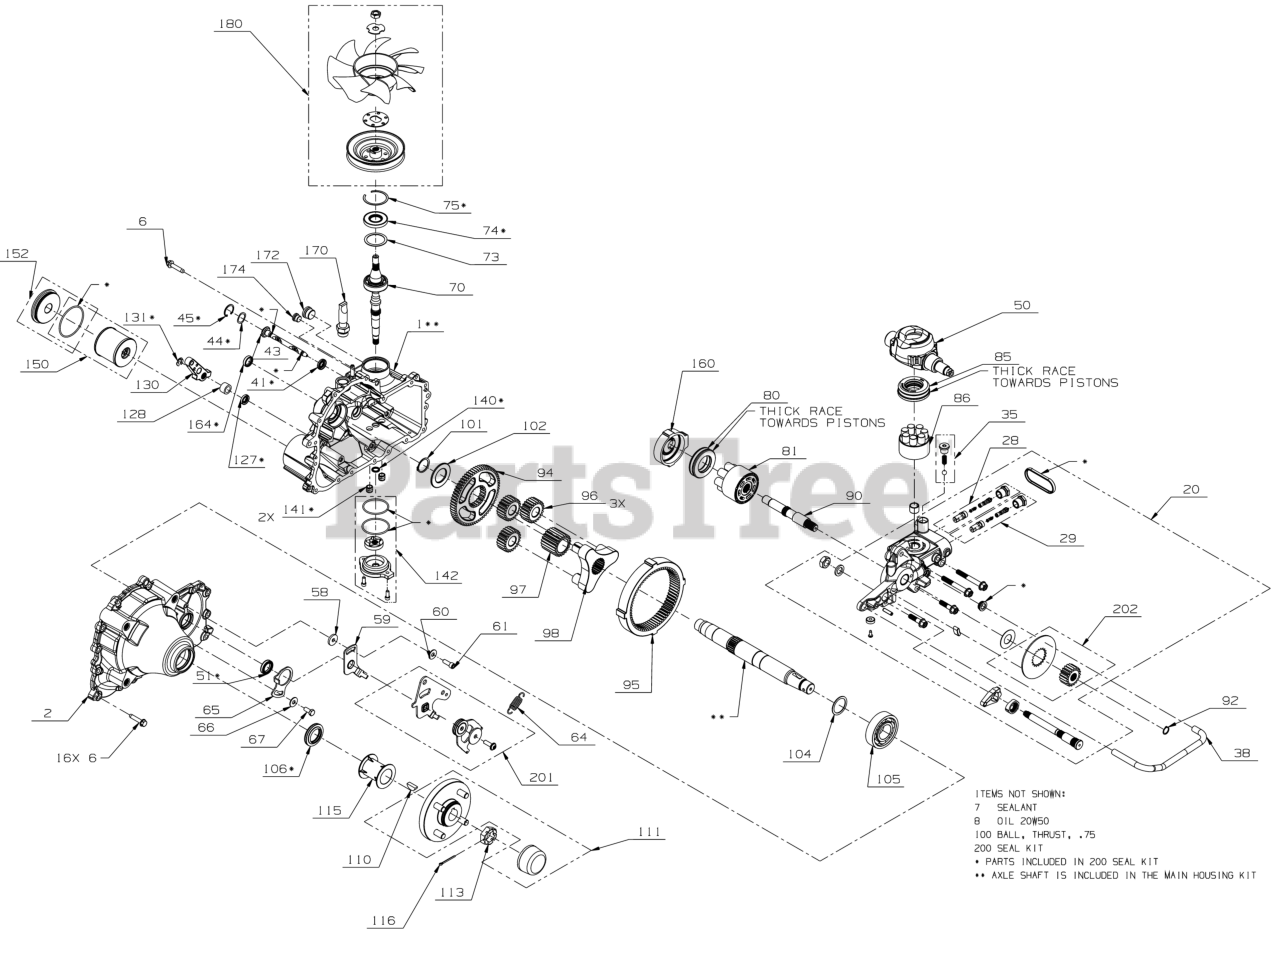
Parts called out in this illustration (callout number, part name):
1	MAIN (RH) KIT
2	SIDE HOUSING (RH) KIT
6	HOUSING SCREW
7	SEALANT-HOUSING
20	CENTER SECTION (RH) KIT
28	SHOCK VALVE KIT
29	SHOCK VALVE KIT
35	CHARGE RELIEF KIT
38	FILTER TUBE-RH
41	LIP SEAL 12 X 24 X 5
43	ACTUATOR BYPASS ASM
44	WAVE WASHER 1.00 X .78 X .07
45	RETAINING RING HO-102
50	16CC MACHINED SWASHPLATE
51	LIP SEAL 22 X 32 X 7
58	SPACER .32 x 1.005 x .179
59	ARM-NEUTRAL (RH)
60	FLAT WASHER
61	SCREWS KIT-RTN
64	EXTENSION SPRING
65	STOP PLATE-RH
66	FLAT WASHER
67	SCREW 5/16-18.75 HHCS
70	INPUT SHAFT KIT
73	FLAT WASHER 1.559X1.944X.040
74	LIP SEAL 25 X 52 X 7
75	RETAINING INTERNAL RING
80	PLASTIC THRUST BEARING
81	BLOCK KIT-21CC CYL
85	THRUST BEARING
86	16CC CYLINDER BLOCK KIT
90	MOTOR SHAFT
92	RETAINING RING
94	65T/22T GEAR
95	RING GEAR 68T
101	RETAINING RING
102	AXLE GEAR SPACER
104	FLAT WASHER 1.40 X 1.75 X .05
105	BALL BEARING 35 X 80 X 21
106	LIP SEAL 1.375 X 2.062 X .250
110	WOODRUFF KEY 5/16 X 1
111	4 BOLT HUB KIT
113	SLOTTED 1-20 NUT
115	AXLE TUBE 1.40 X 2.22
116	COTTER PIN 9/64 X 1.5
127	LIP SEAL .562 X .875 X .18
128	SPACER-.57 X .86 X .53
130	ACTUATING HANDLE
131	RETAINING RING
140	LIP SEAL .500 X .688 X .094
141	TUBE-CHARGE TRIPLE O-RING
142	CHARGE COVER KIT
150	FILTER KIT
152	FILTER PLUG KIT
160	MOTOR SWASH PLATE
164	PLUG SEAL .945 X .250
170	STRAIGHT FITTING 7/8 SAE
174	PLUG-STRAIGHT THRE
180	FAN/PULLEY KIT
200	OVERHAUL SEAL KIT
201	RTN BI-DIRECTIONAL KIT
202	BRAKE ROTOR,GEAR KIT
